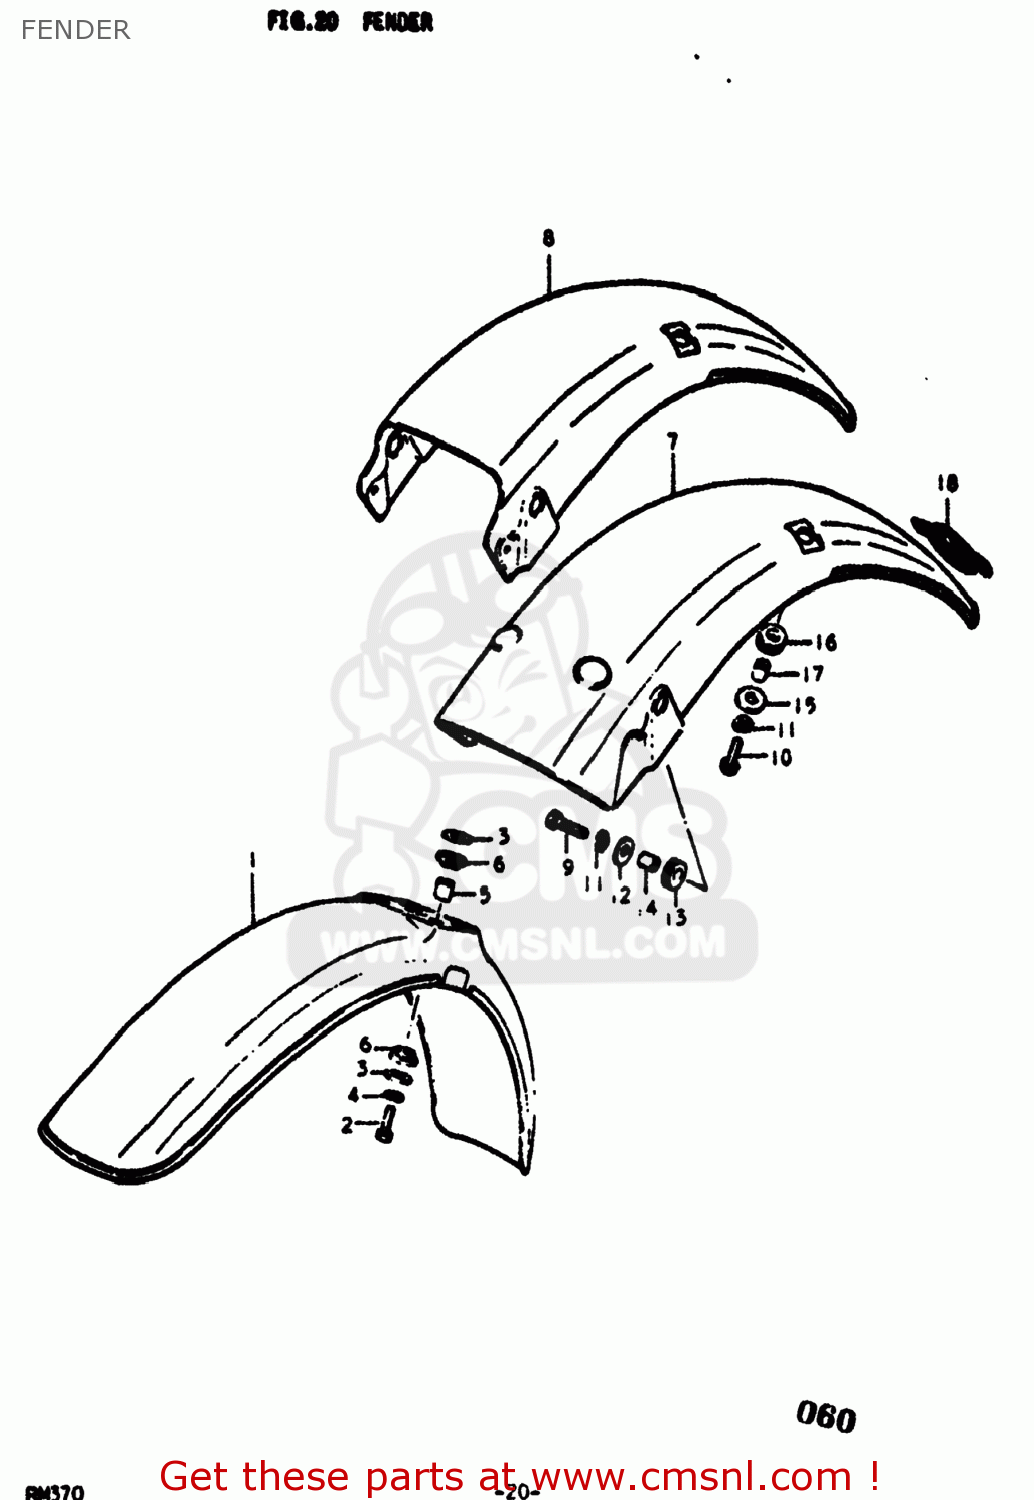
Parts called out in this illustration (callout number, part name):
1	FENDER,FRONT
2	BOLT
3	WASHER (6.5X20X1.2)
4	LOCK WASHER
5	SPACER (6.8X10X10)
6	CUSHION
7	FENDER,REAR
8	FENDER,REAR
9	BOLT
10	BOLT
11	LOCK WASHER
12	WASHER (6.5X20X1.2)
13	CUSHION
14	SPACER(6.1X9X7.5)
15	WASHER (6.5X24X1.6)
16	CUSHION
17	SPACER
